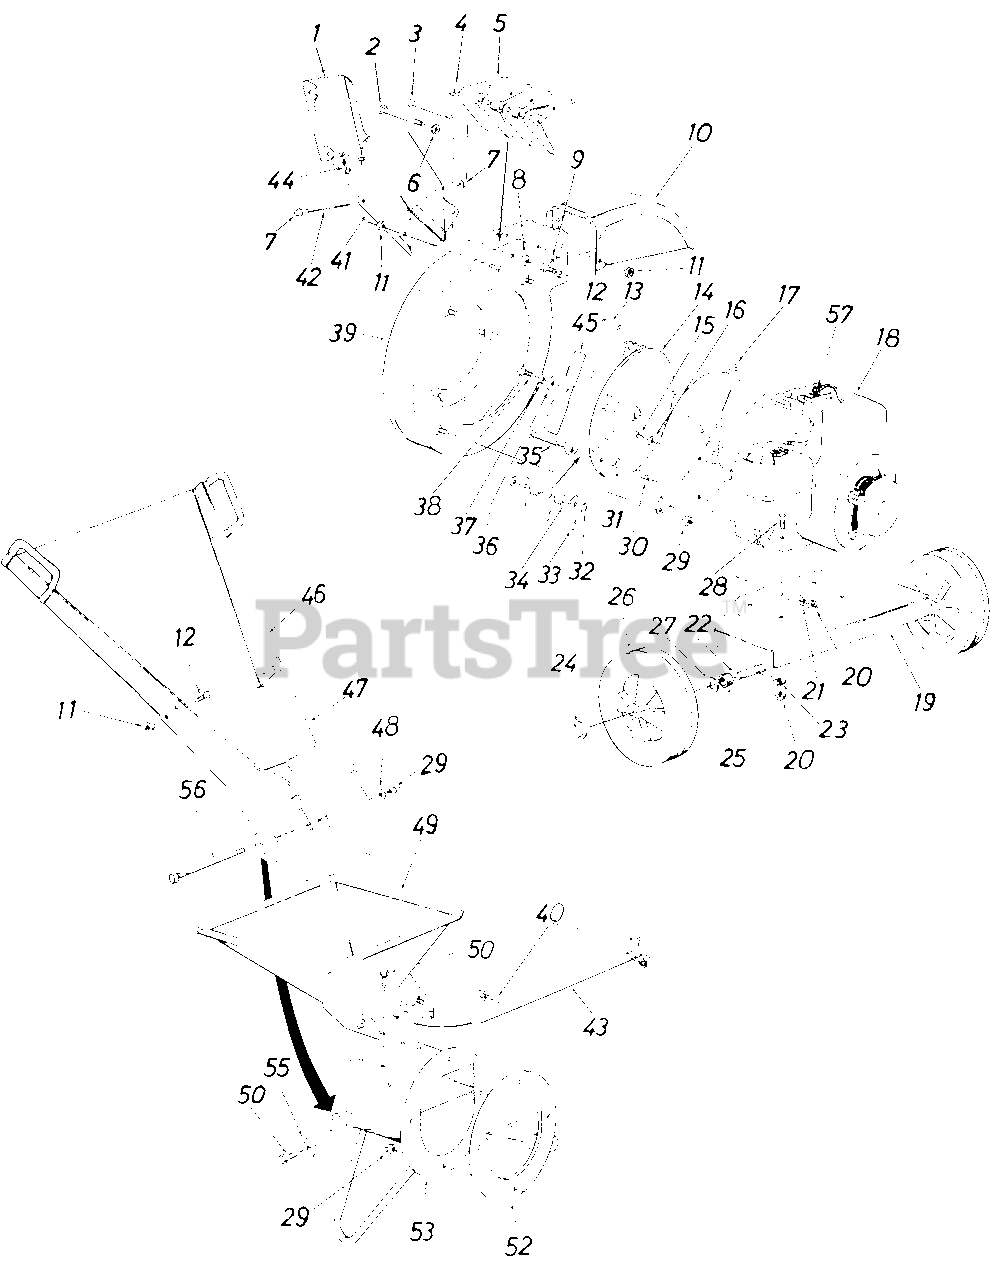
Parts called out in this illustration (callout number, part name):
1	Door Chip It
2	Hex Bolt 1/2-20 x 4.50" Lg.
3	Clevis Pin
4	Flail Spacer 7/32" Lg.
5	Cutting Finger
6	L-Wash. 1/2" I.D.
7	Palnut 3/16" Dia.
8	Hex Jam Nut 1/2-20 Thd.
9	Cotter Pin 3/32" Dia. x 3/4" Lg.
10	Chute Deflector
11	L.-Nut 1/4-20 Thd.
12	Hex Bolt 1/4-20 x .50" Lg.
13	Sq. Key 1/4" x 2.00" Lg.
14	Impeller Assembly
15	Hex Bolt 5/16-24 x 3/4" Lg.
16	L.-Wash. 5/16" I.D.
17	Hopper to Engine Mtg. Plate
18	Engine
19	Engine Mounting Plate
20	Hex Nut 5/16-24 Thd.
21	L.-Wash. 5/16" I.D.
22	Shaft
23	Special L.-Wash. 5/16" I.D.
24	Push Cap
25	Spacer
26	Wheel Ass'y.-Comp.
27	Fl.-Wash. .50" I.D.
28	Hex Bolt 5/16-24 x 1.50" Lg.
29	Elastic Lock Nut 5/16-18 Thd.
30	Hex Bolt 5/16-24 x .62" Lg.
31	Cotter Pin 1/8" Dia. x 1.00" Lg.*
32	Fl.-Wash. .531" I.D. x 937 O.D. x .09
33	Flail
34	Flail Spacer 23/32" Lg.
35	Clevis Pin .50" Dia. x 3.0" Lg.
36	Fl.-Wash. .406" I.D. x 1.25" O.D. Hdn.
37	L.-Wash. 3/8" I.D. H.D.
38	Hex Bolt 3/8-24 x 2.0" Lg. H.T.
41	Chip-lt Guide Ass'y.
42	Hinge Pin
43	Release Bar
44	Wing Nut Elastic 1/4-20 Thd.
47	Lower Leaf Ramp Section
48	Fl.-Wash. 5/16" I.D.
49	Hopper Assembly
50	Hex Wash. Hd. Self-Tap Scr. 5/16-18 x .75" Lg.
52	Back-Up Plate
53	Inlet Guide Assembly
55	Stop Washer
56	Hex Bolt 5/16-18 x 8.38" Lg.
57	Spark Plug Elbow
